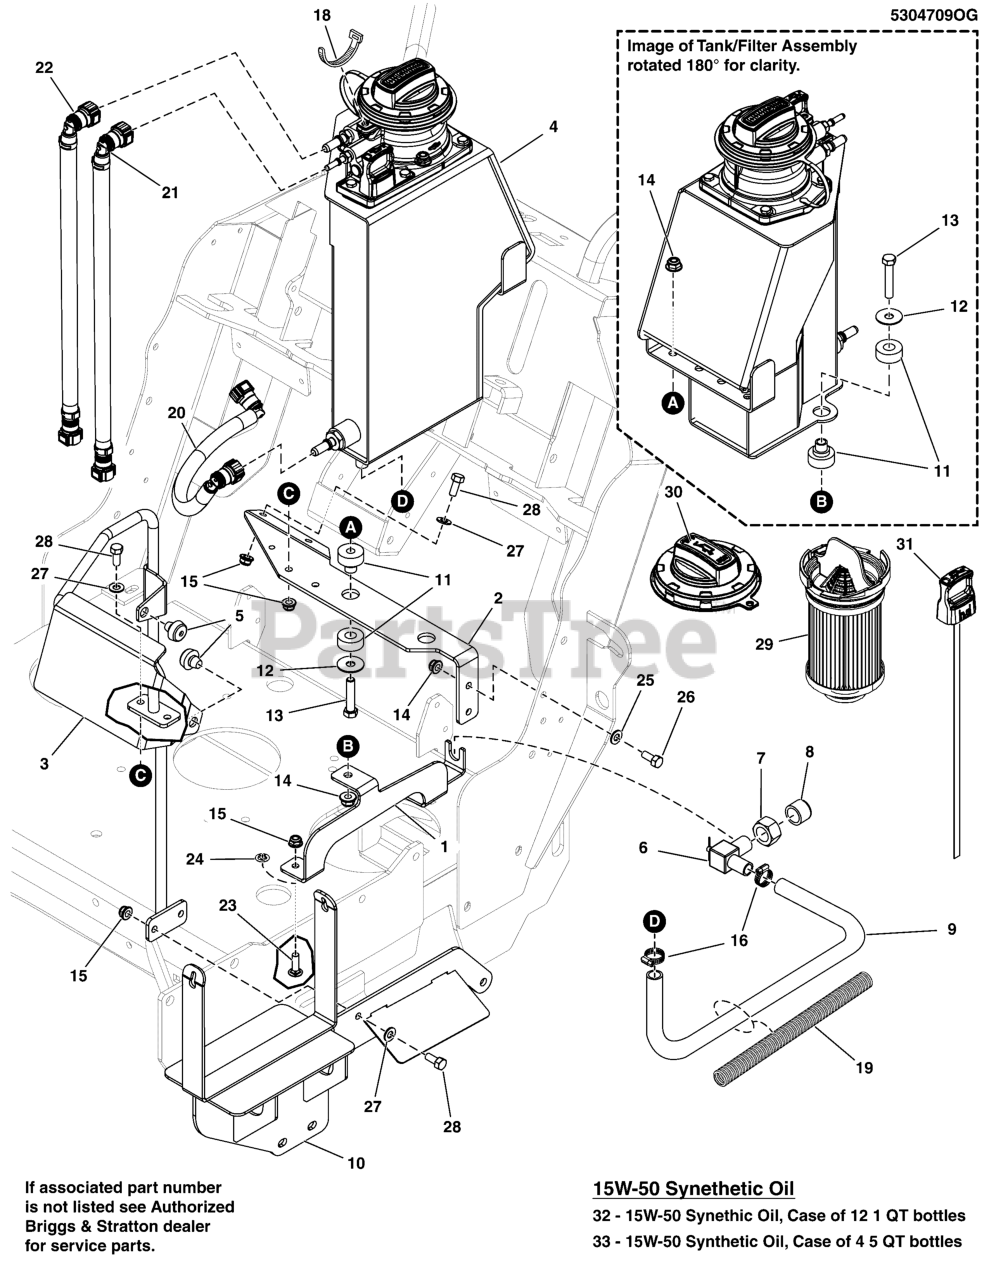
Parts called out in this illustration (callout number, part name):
1	PLATE, LOWER TANK MOUNT, W45 - BLK
2	TANK MOUNT, TOP, W35 - BLK
3	WELD, TANK GUARD, W35 - BLK
4	TANK, Oil
4	TANK, OIL
5	MNT, VBRTN, RBBR
6	VALVE, OIL DRAIN, M16X1.5 TO 1/2"
7	NUT, HEX, M16-1.5, DAPCO 4071
8	OIL DRAIN CAP, OIL GUARD, DAPCO 4692
9	HOSE, Formed, Oil Guard
10	Refer to: Electrical Group
11	MOUNT, ISO, BOTTOM, RAD 5000Z-DIESEL
12	WASHER, 3/8" Fender
13	BOLT, 3/8-16 X 1-3/4" GD5 CZ
14	NUT, 3/8 - 16 HEX NYLOCK FLANGE
15	NUT, 5/16-18 HEX NYLOCK FLANGE NUT
16	CLAMP, #6 HOSE, STAINLESS
19	WIRE LOOM, 3/4 ID X 8.00" LG
20	HOSE, OIL SUPPLY
21	HOSE, Oil Vent
22	HOSE, OIL SCAVENGE
23	BOLT, 5/16-18 X 1, CARRIAGE, GD5, CZ
24	5/16" PUSH-ON NUT RETAINER, STL, CZ
25	WASHER, 3/8 SAE
26	BOLT, 3/8-16 X 1-1/4" GD5 CZ
27	WASHER, 5/16" SAE
28	BOLT, 5/16-18 X 1" GRD5 YZ
29	FILTER, OIL
30	CAP, Oil Fill
31	DIPSTICK
32	OIL, 15W-50, SYNTHETIC, CASE X 12- 1QT
33	OIL, 15W-50, SYNTHETIC, CASE X 4- 5QT
